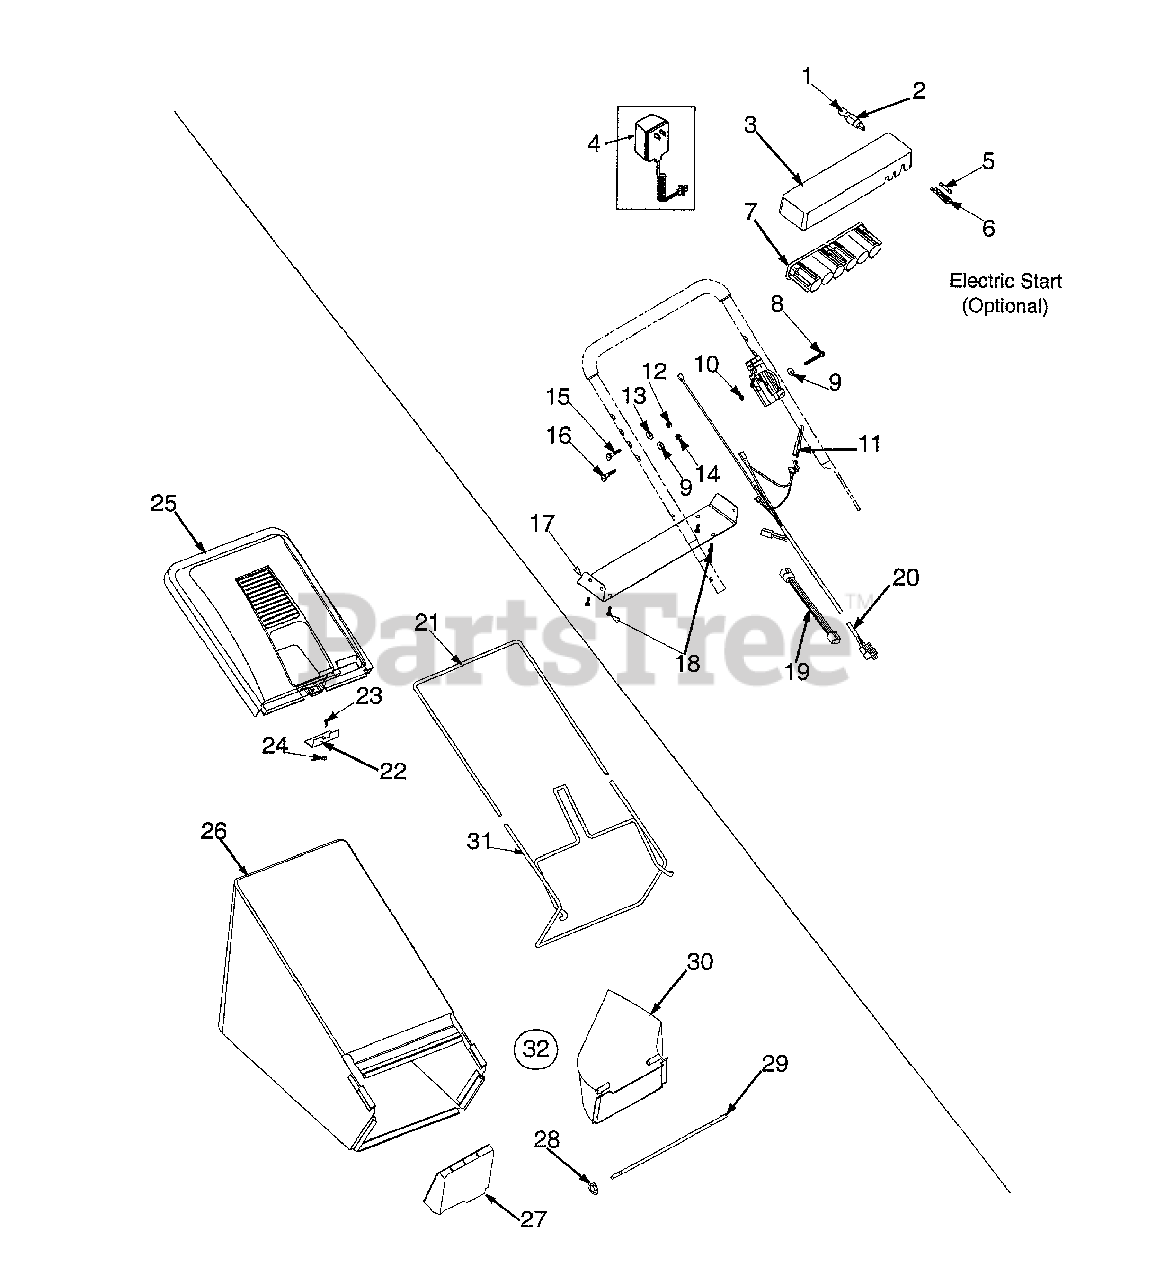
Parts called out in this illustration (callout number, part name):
1	Ignition Key
2	Key Switch
3	Battery Tray
4	Battery Charger
5	Fuse 7.5 Amp
6	Fuse Holder
7	Battery 12V
8	Hex Screw: 1/4-20:2.0
9	Bell Washer .265 x .75 x .062
10	Special Hex Nut 5/16-18
11	Plug
12	Nut 5/16-18
13	Bell Wash .340 1 D x .872 OD
14	Hex Nut 1/4-20
15	Carriage Bolt 5/16-18 x 1
16	Carriage Screw
19	Harness Extension
20	Harness
23	Hex Screw 1/4 -20 x.5
24	Hex Nylon L-Nut 1/4-20
25	Hardtop Cover w/o Logo: Blk.
26	Grass Bag: Soft Top w/ Logo
27	Mulcher Plug
28	Nut: Spd. .3125 ID
30	Side Discharge Adapter
